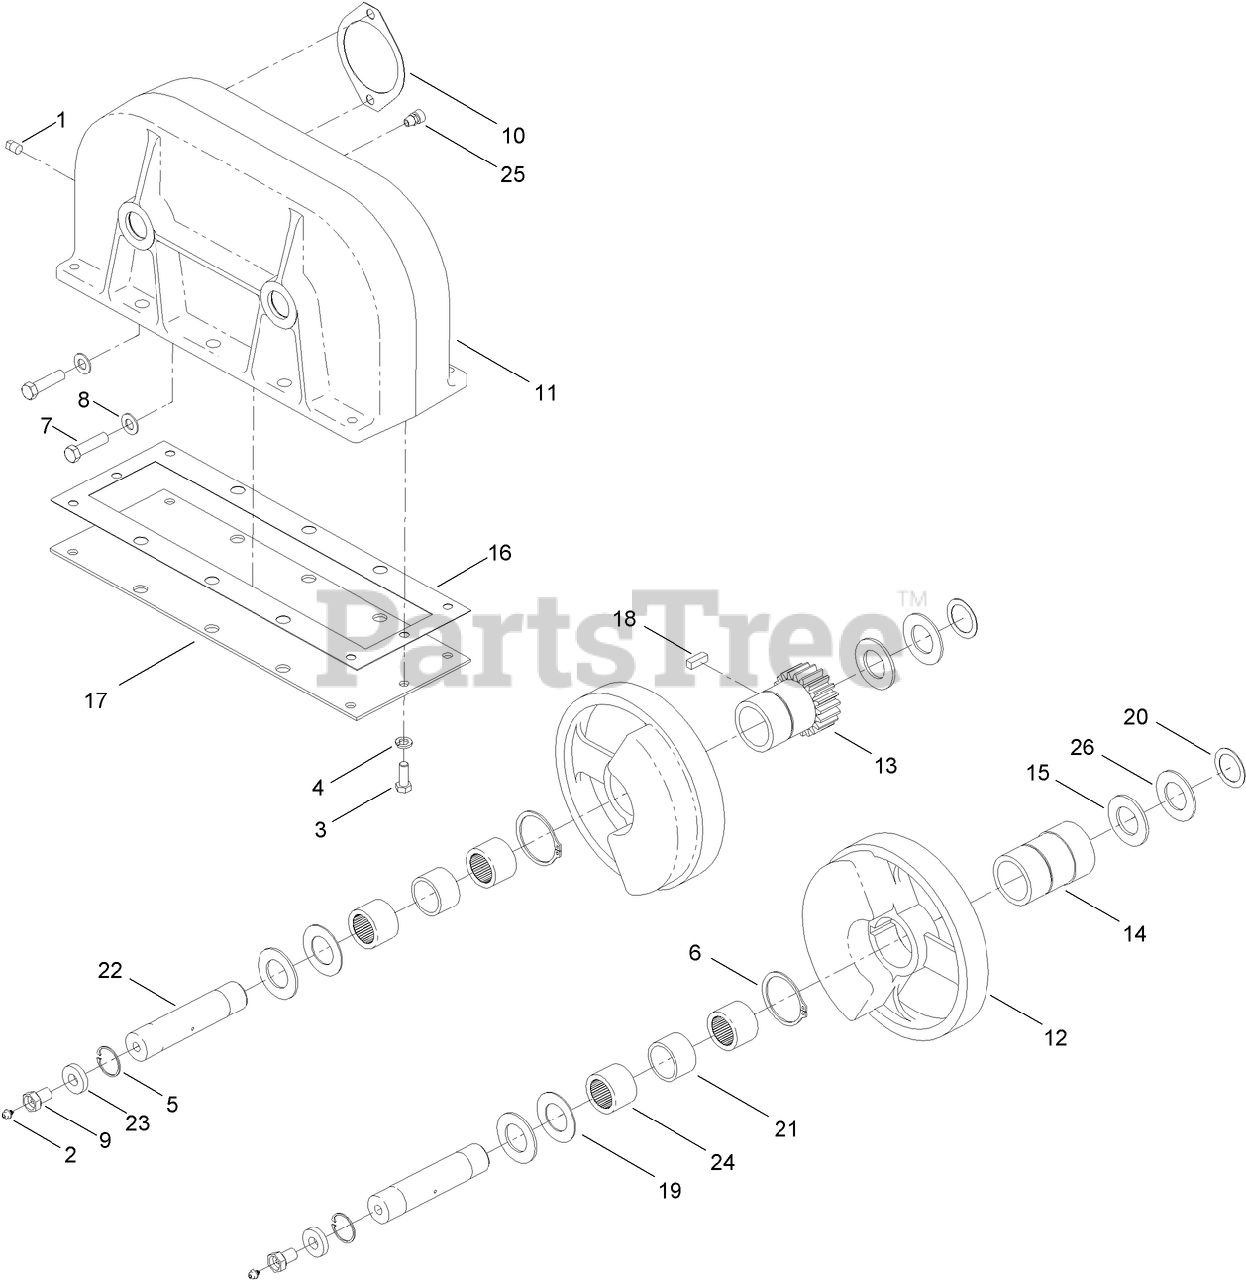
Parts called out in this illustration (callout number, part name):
1	CAP-PIPE
2	FITTING-GREASE, ZERK
3	SCREW-HH
4	WASHER-LOCK
5	RING-RETAINING
6	RING-RETAINING
7	SCREW-HH
8	WASHER-FLAT
9	ADAPTER-LOCATING
11	CASE-GEAR
13	HUB-DRIVE, BEARING
14	HUB-BEARING
15	WASHER-10 GAUGE
16	GASKET-GEARBOX
17	PLATE-COVER
18	KEY-SQUARE
19	WASHER-THRUST
22	PIN-BEARING
23	WASHER-FLAT, STEPPED
24	BEARING-PITCH LINE
25	VENT-AIR
26	WASHER-THRUST
